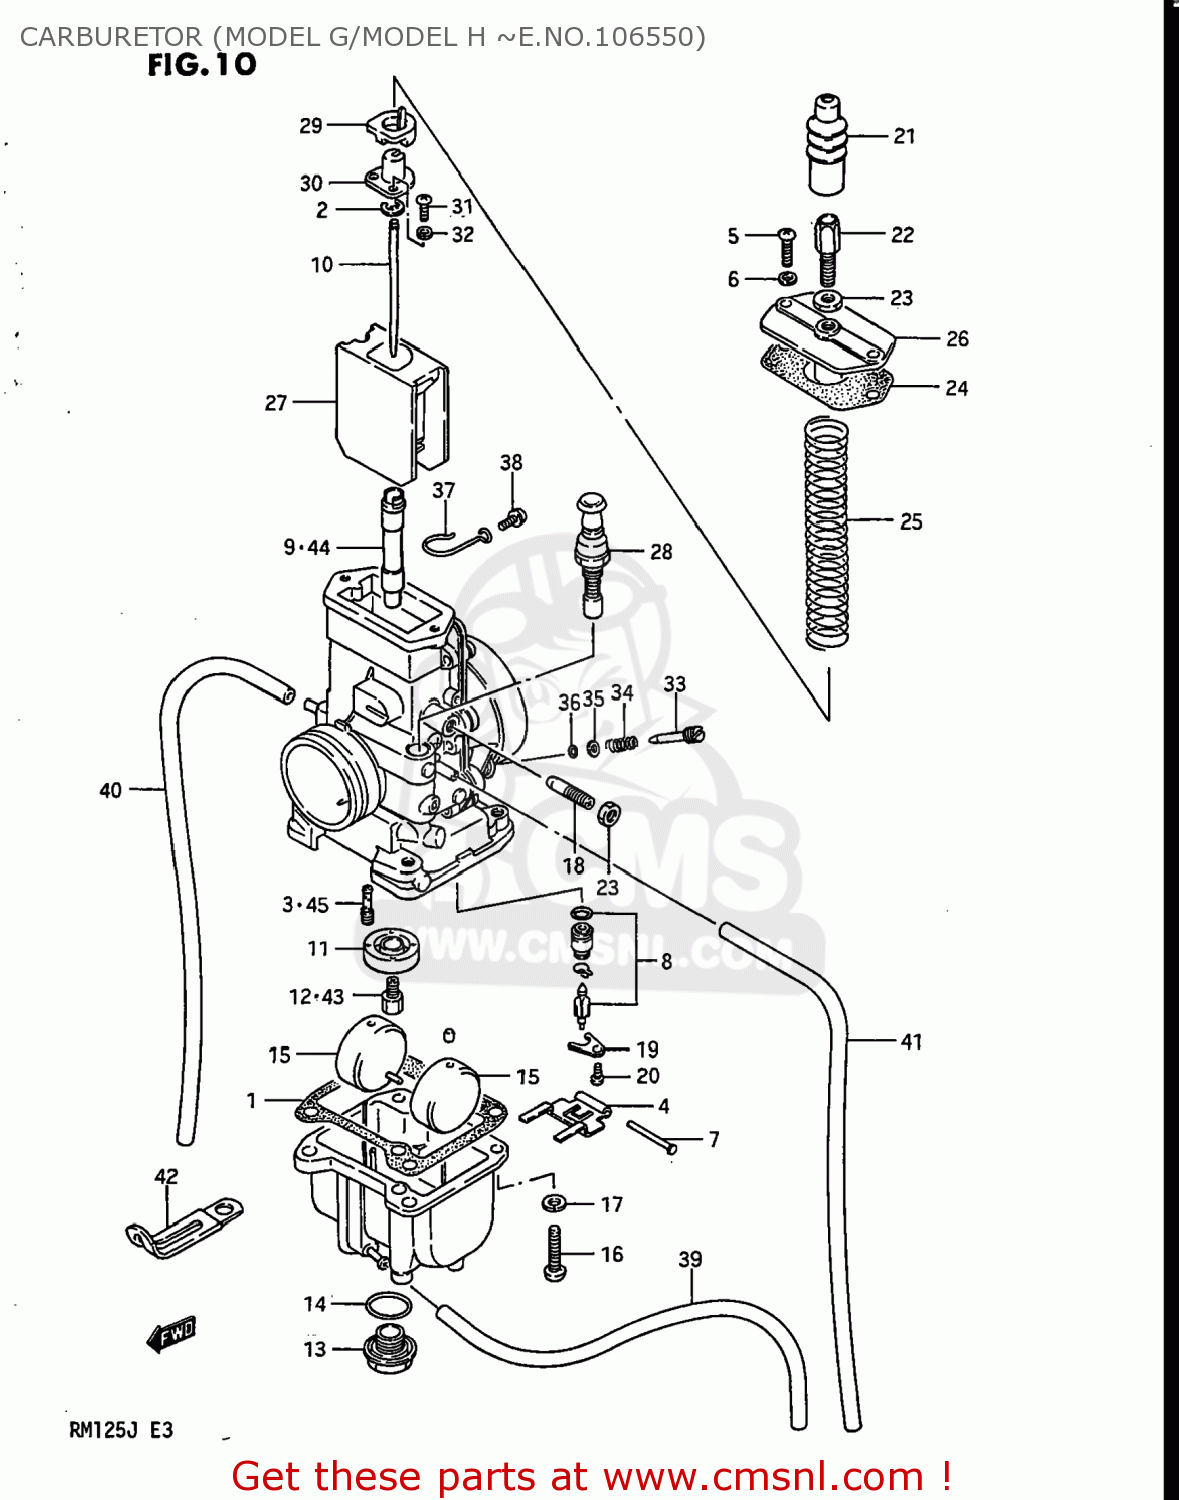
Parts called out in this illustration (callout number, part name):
1	GASKET,FLOAT CAHMBER (NAS)
2	CLIP
3	JET,PILOT
4	ARM,FLOAT
5	SCREW
6	LOCK WASHER
7	PIN,FLOAT
8	VALVE ASSEMBLY,NEEDLE
9	JET,NEEDLE
10	NEEDLE,JET
11	RING,MAIN JET FITTING
12	JET
13	SCREW,GUIDE
14	O RING,DRAIN PLUG
15	FLOAT
16	SCREW
17	LOCK WASHER
18	SCREW,THROTTLE SCREW
19	PLATE
20	SCREW
21	CAP,CABLE ADJUSTER
22	ADJUSTER,CABLE
23	NUT
24	GASKET,TOP (NAS)
25	SPRING,THROTTLE VALVE
26	CAP,CARBURETOR,TOP
27	VALVE,THROTTLE
28	PLUNGER ASSEMBLY
29	RING
30	JOINT
31	SCREW
32	LOCK WASHER
33	SCREW,PILOT AIR
34	SPRING,THROTTLE SCREW
35	GASKET
36	O-RING
37	CLIP
38	SCREW
39	HOSE
40	HOSE
41	HOSE
42	CLAMP L:35
43	JET
44	JET,NEEDLE
45	JET,PILOT
